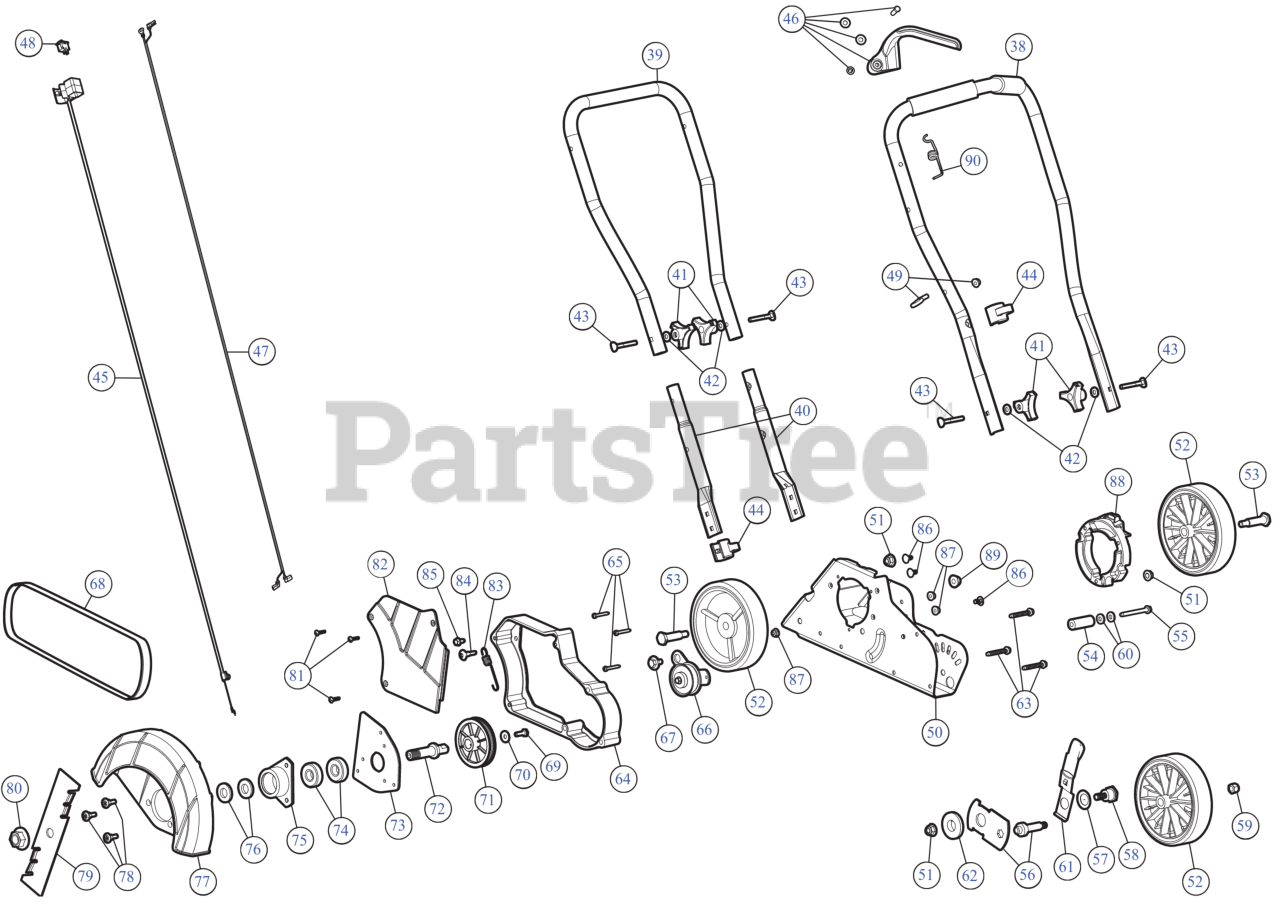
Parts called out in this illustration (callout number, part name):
38	HANDLE UP
39	HANDLE MID
40	HANDLE EXT
41	KNOB, 3-PRONG ¼ "-
42	WASH, FLAT SPECIAL
43	BOLT, CARRIAGE CRV
44	CABLE GUIDE
45	THROTTLE CABLE
46	THROTTLE LVR W/HDW
47	WIRE LEAD
48	SW, MOMENTARY ON/O
49	ROPE GUIDE
52	WHEEL 5-1.5 GRAY
53	SHOULDER SCREW
54	SPACER
55	SCREW 1/4-20 x 2.375
56	PIVOT ARM
57	BELL WASHER
58	SHOULDER SCREW .75 X.50 X3/8-16
59	HEX NUT INS L-3/8-16
60	SPACER
61	FRONT HEIGHT ADJUST LEVER ASSEMBLY
62	HEIGHT ADJUSTMENT BEARING
63	SCREW 1/4-20 x 1.750
64	SPACER
65	SCREW 8-16X1.25
66	IDLER PULLEY ASSEMBLY
67	SHOULDER SCREW .560X.165: 5/16-18
69	SCREW 1/4-20X.75 GR5
70	SPRING WASHER BELL
72	BLADE SPINDLE
73	SPINDLE MOUNT PLATE
74	BALL BEARING
75	BEARING CUP
76	FLAT WASHER .635X1.24X.181
77	EDGER BLADE GUARD (W/LABEL)
78	SHOULDER SCREW .375X.280:1/4-14
79	EDGER BLADE
80	HEX NUT
81	SCREW 8-16 x 3/4
82	BELT COVER
83	SPRING
84	BOLT 1/4-20
85	SCREW 1/4-20 X.500
86	CARRIAGE BOLT 1/4-20X.50"
87	FLANGE LOCK NUT
88	SPACER
90	SPRING
